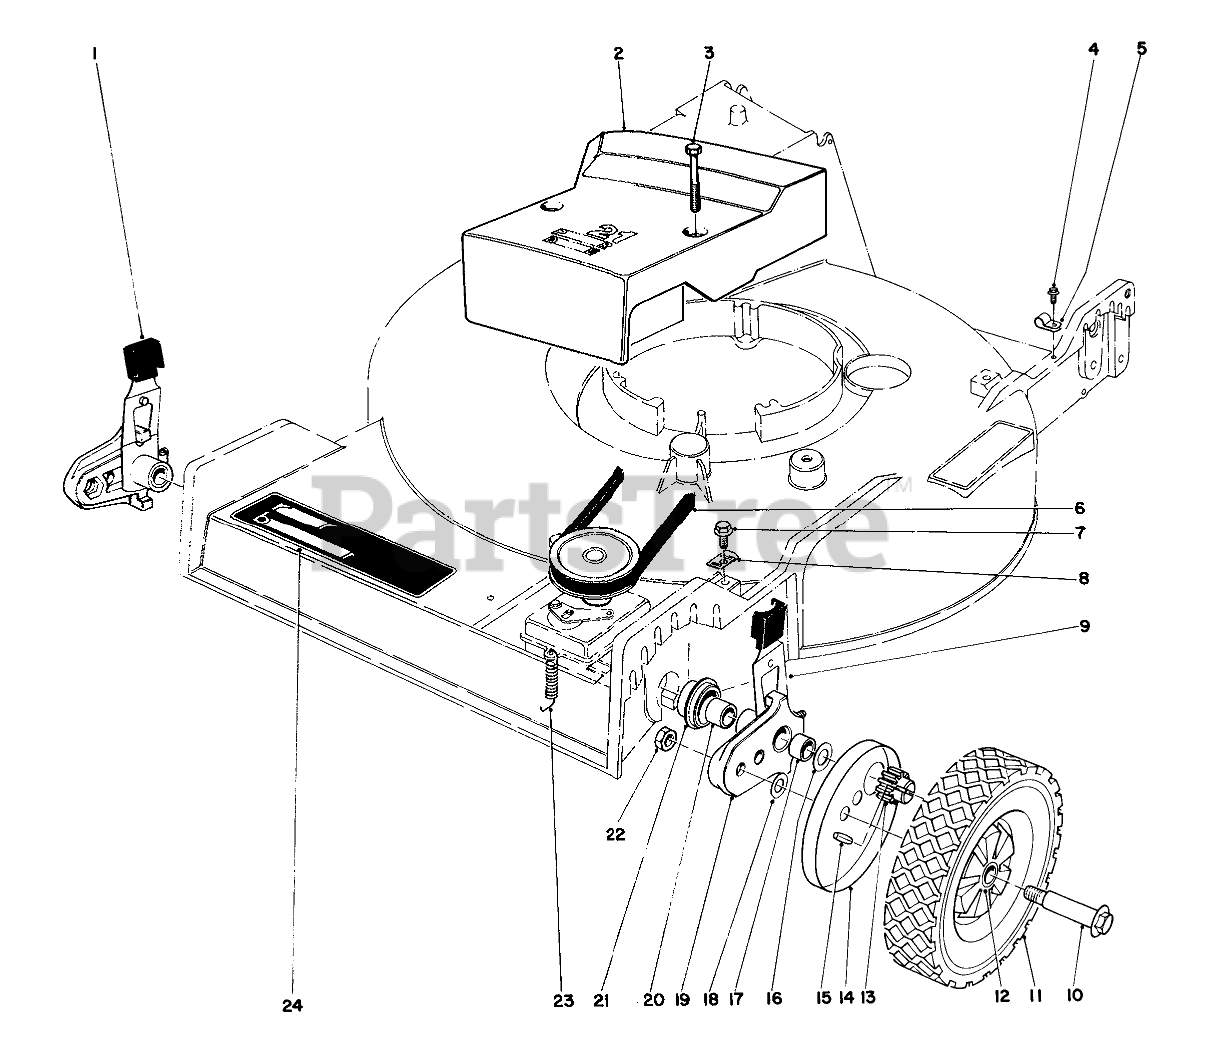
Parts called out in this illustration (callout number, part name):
1	KNOB-ARM
2	Cover-Belt
3	Screw-Thread Cutting
4	SCREW
5	CLAMP-CABLE
6	V BELT
7	SCREW-HWHTF
8	Cable Clamp
9	SPRING ARM ASM SP
10	BOLT-WHEEL
11	Wheel Assembly (Incl. Ref. #12)
12	BUSHING
13	PINION GEAR 15T
14	Cover-Wheel
15	Pin
16	THRUST WASHER
17	Bushing
18	WASHER
19	Pivot Arm (Incl. Ref. #17 & 20)
20	Bushing
21	End Cap
22	Nut
23	TENSION SPRING
24	Decal-Deck
